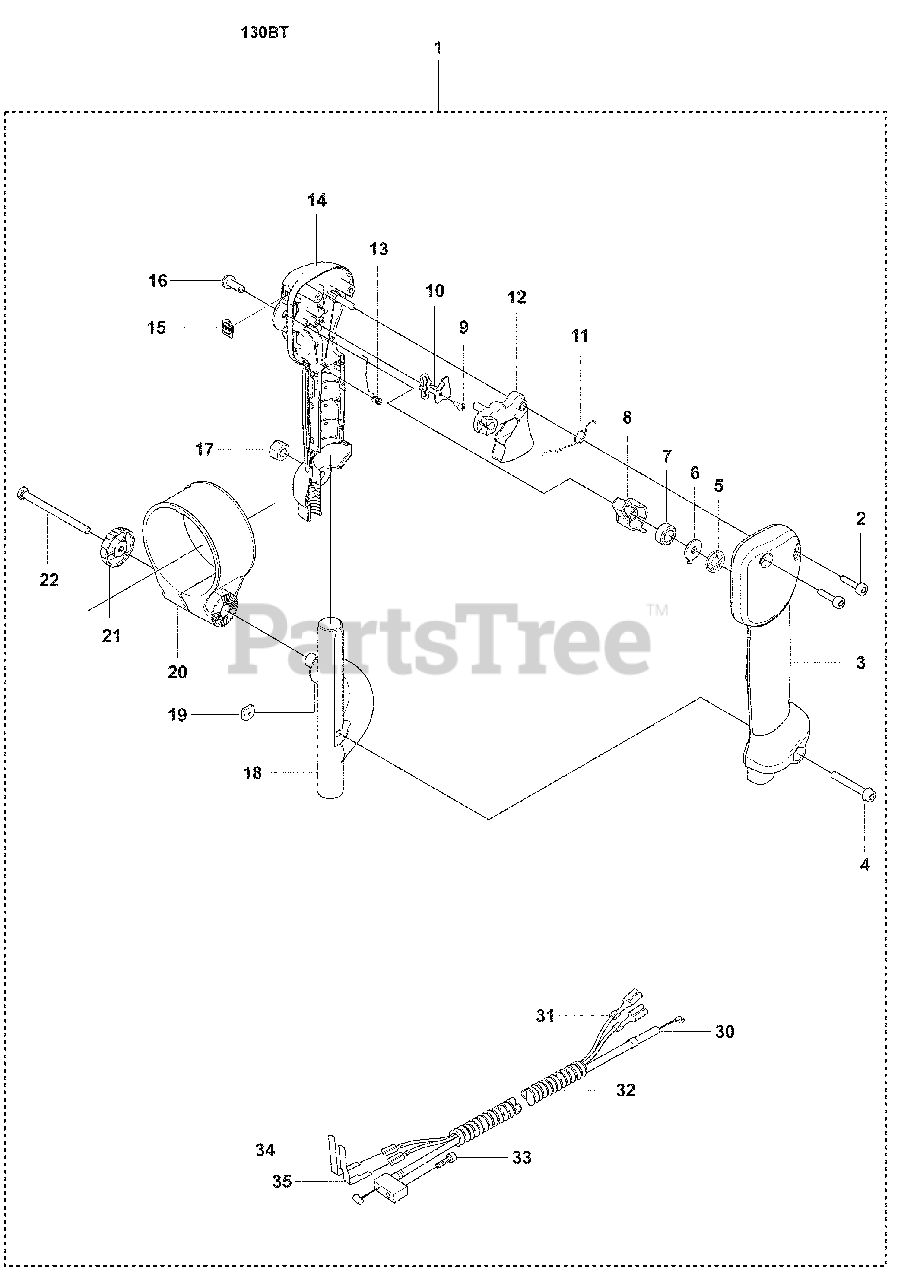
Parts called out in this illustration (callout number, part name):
1	Handle Assembly
3	Right Half Handle
4	Screw, Ihscfm M5 X 35 10.9 ZP
7	Spring, Rubber
8	Stop Lever
14	Left Half Handle
19	Square Nut
20	Holder, TH
21	Air Filter Cover Knob
31	Cord
32	THROTTLE CABLE
34	Contact Spring
35	Contact Spring
